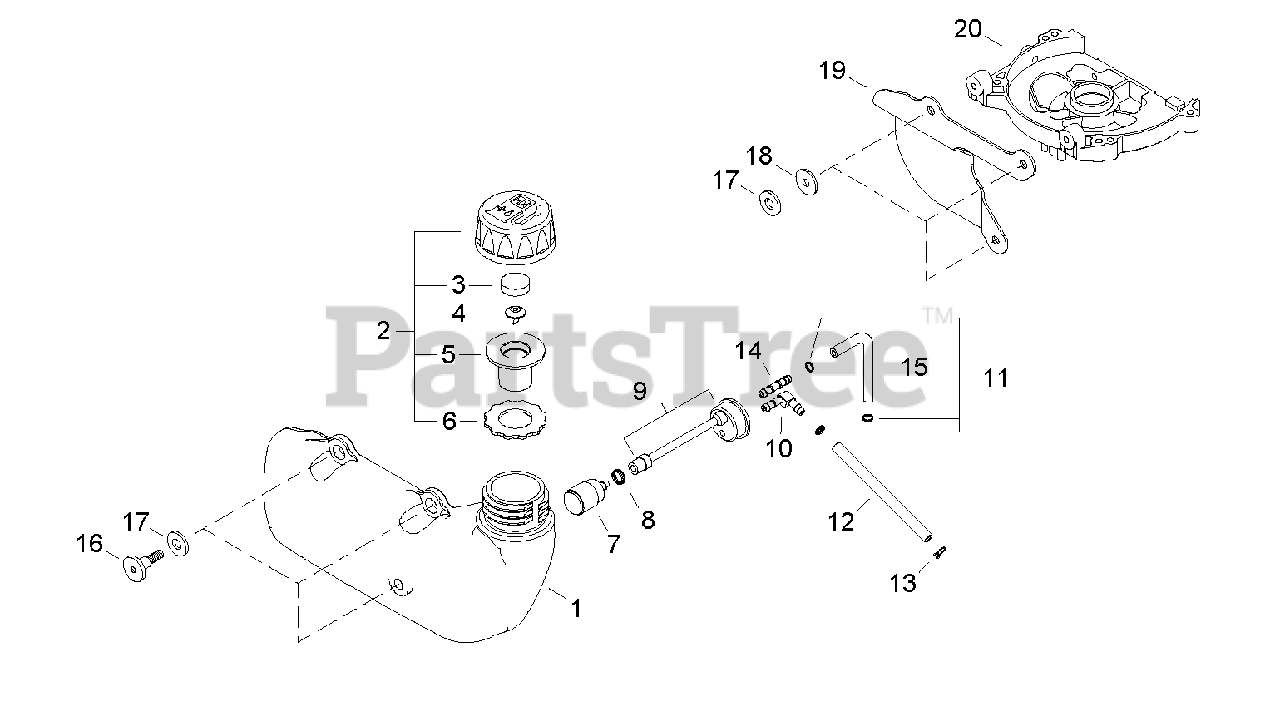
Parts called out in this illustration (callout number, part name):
1	TANK, FUEL
2	CAP, FUEL
3	PACKING, VENT
4	VENT ASSY
5	HOLDER, VENT
6	GASKET, FUEL CAP
7	FILTER, FUEL 125-528
9	GROMMET, FUEL WITH PIPE
10	CONNECTOR, PIPE
11	CLIP Ø6
12	PIPE, FUEL RETURN
13	CLIP, SPRING Ø5.2
14	CONNECTOR, PIPE
15	PIPE, FUEL
16	BOLT, ADHESIVE 5
17	WASHER 6
18	WASHER 5
19	SHIELD, HEAT
20	CRANKCASE ASSY, M
